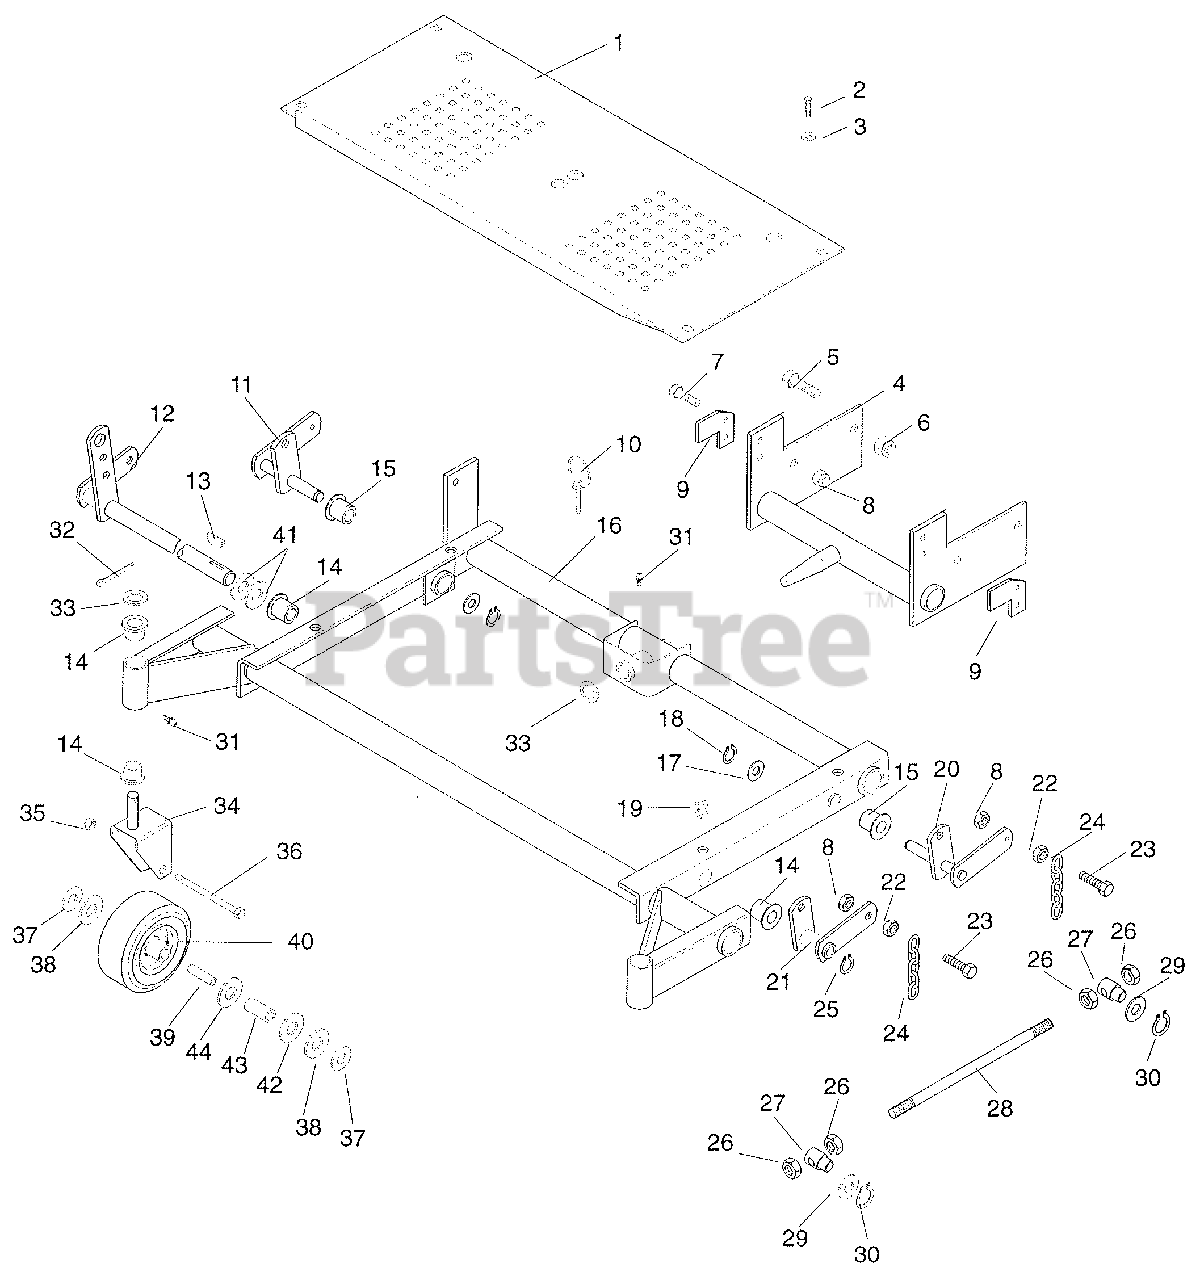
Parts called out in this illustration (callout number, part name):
1	Footboard PM200
2	Screw Machine .25-20
3	Washer Flat Steel .281 X .625 X .065
4	Weldment, Mower Frame Mounting
5	Fbolt Hex .625-11 X 1.50
6	Nut Locking Nylon .625-11
7	Bolt Hex .38-16 X 1.125
8	Nut Lockijng Nylon .375-16 Grade 2
9	Plate, Pivot Stop
10	Pin Klik .25 X 1.75
11	Weldment, Lift Arm Shaft
12	Weldment, Mower Lift Shaft (front)
13	Key Woodruff .25-1.0
14	Bushing Flange 1.020 X 1.385 X .75 X 1.75
15	Bushing Flange .762 X 1.0 X .580 X 1.48
16	Weldment, Front Frame PM200
17	Bearing N Thrust .752 X 1.24 X .031
18	Ring Retaining External .689 X .077
19	Clip, U-Type
20	Weldment, Lift Arm Shaft RH
21	Weldment, Lift Arm (Front)
22	Nut Hex .375-16 Grade 2
23	Bolt Hex .38-16 X 1.50 Grade 5
24	Chain, Link
25	Ring Retaining External 1.00 X .078
26	Nut .50-13
27	Pivot, Mower Lift
28	Tie Rod, Lift Lever
29	Washer Flat Steel .630 X 1.005 X .062
30	Ring Retaining External .625 X .050
31	Fitting Lub .25-28 X .256
32	Pin Cotter .12 X 1.25
33	Bearin R Thrust 1.022 X 1.552 X .030
34	Weldment, Caster Fork
35	Nut Locking Nylon .50-13 Grade 2
36	Bolt Hex .500-13 X 8.00
37	Washer Flat Steel .531 X 1.250 X .100
38	Washer Flat Steel .813 X 1.370 X .100
39	Axle, Caster
40	Tire/Wheel Assembly 13 X 5-6
41	Washer Flat Steel .063 X 2.000 X .134
43	Bearing, Roller
44	Stop Washer
NS	Tire, 13 X 5-6 Turf Trac
